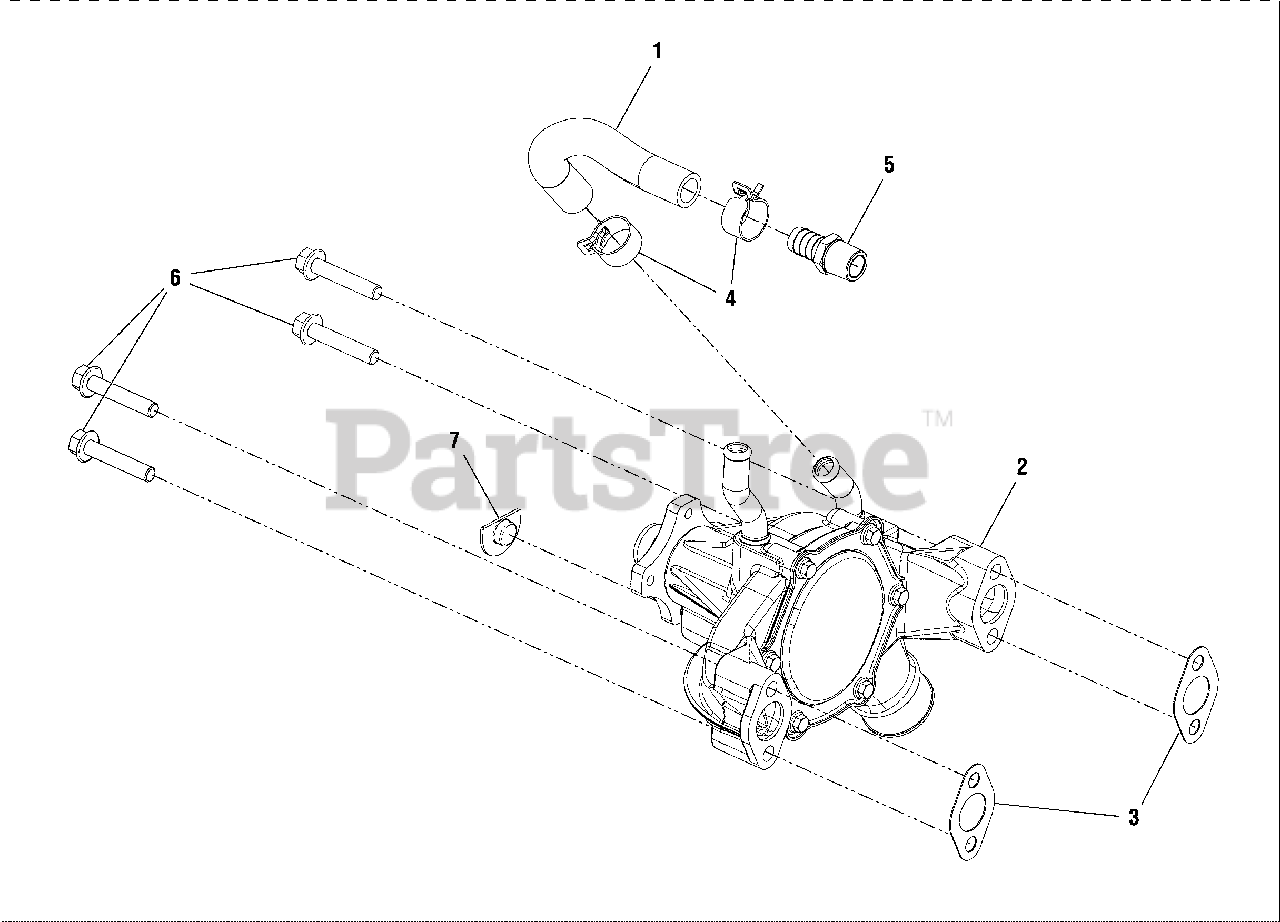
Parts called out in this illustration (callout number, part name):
1	HOSE, W/PUMP
2	PUMP, WATER
3	GASKET, WATER PUMP
5	FITTING, BARB
6	BOLT
7	SEAL
